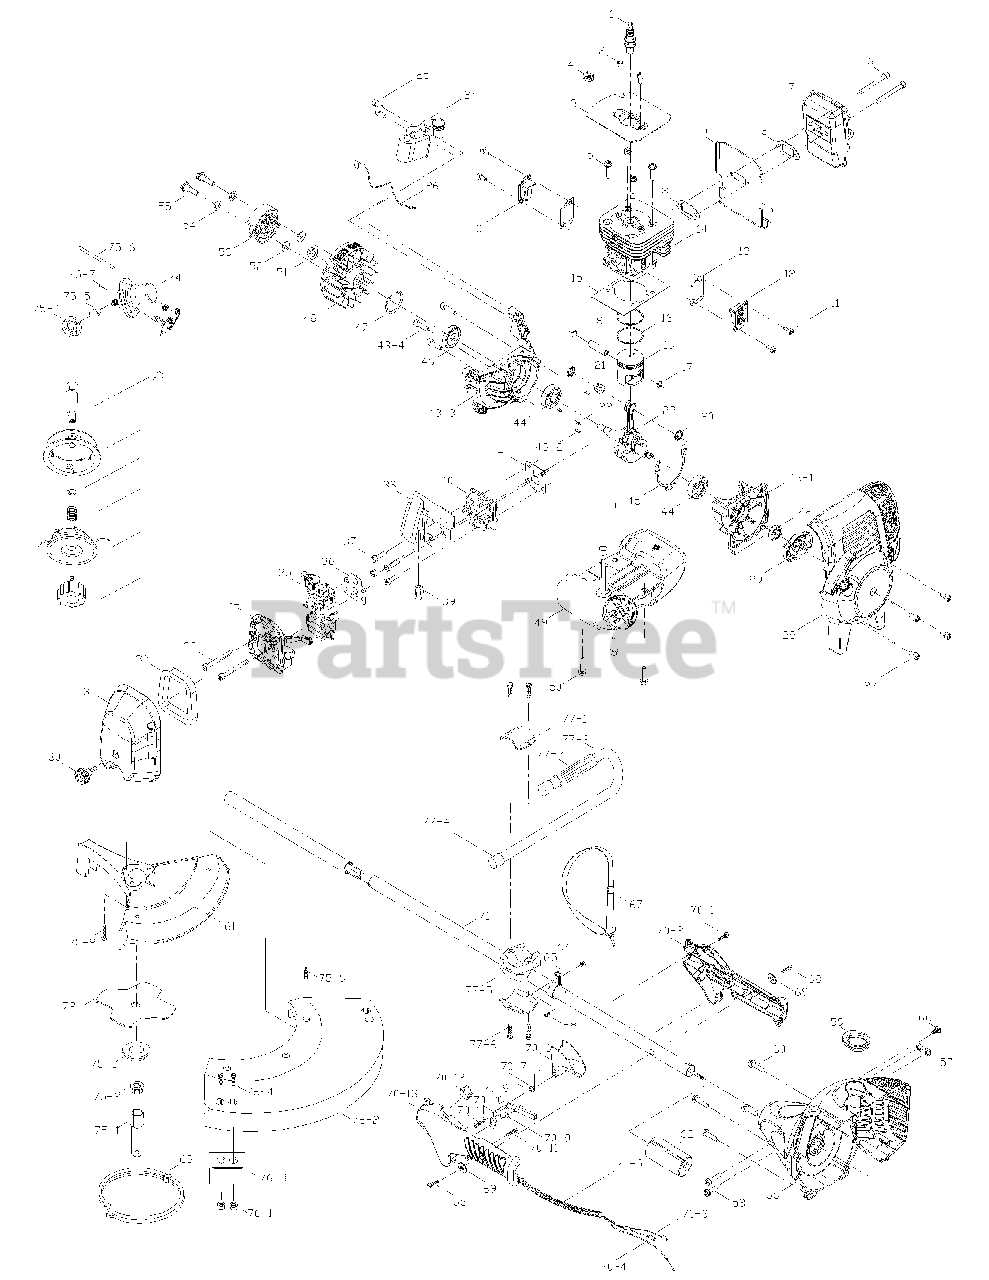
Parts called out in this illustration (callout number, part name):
1	SPARK PLUG
3	PLATE (SPARK SIDE)
7	MUFFLE ASS'Y
8	MUFFLE GASKET
9	MUFFLE PLATE
10	COVER (FLYWHEEL SIDE)
14	CYLINDER
16	PISTON RING
18	PISTON PIN
20	AXLS COVER
21	NEEDLE BEARING
23	CRANK/ROD ASS'Y
24	IGNITION COIL
26	COIL WIRE
28	STARTER HOUSING ASS'Y
29	PAWLS ASS'Y
30	KNOB
31	FILTER COVER
34	FILTER ASS'Y
35	CARBURETOR
36	CARBURETOR GASKET
40	INSULATOR
41	INSULATOR GASKET
43	CRANKCASE ASS'Y
43-1	CRANKCASE (STARTER SIDE)
43-3	CRANKCASE (FLYWHEEL SIDE)
47	C RING
49	FUEL TANK ASS'Y
51	NUT
53	CLUTCH (WITH SPRING)
54	WAVE PLATE
56	TRANSMISSION SUPPORT ASS'Y
61	SHIELD, BLADE
63	GUARD, CUTTING BLADE
64	NUT
65	HARNESS RING
70	HANDLE ASS'Y
70-2	HOUSING, HANDLE
70-3	WIRE ASS'Y, SWITCH
70-4	THROTTLE CABLE
70-8	LIBERATE SHAFT
70-10	LIBERATE CHUNK
70-13	HOUSING, HANDLE
71	HOUSING ASS'Y
72	BLADE, BRUSH 4-TOOTH
73	SRTINGHEAD ASS'Y
74	GEAR HOUSING ASS'Y
75	ACCESSORIES
75-3	FLANGE, SPINDLE
75-5	SPLINE SLEEVE
76	COVER ASS'Y
76-3	KIT, KNIFE
77	HANDLE ASS'Y
77-5	CENTERPLECE
77-6	PARTS BAG
